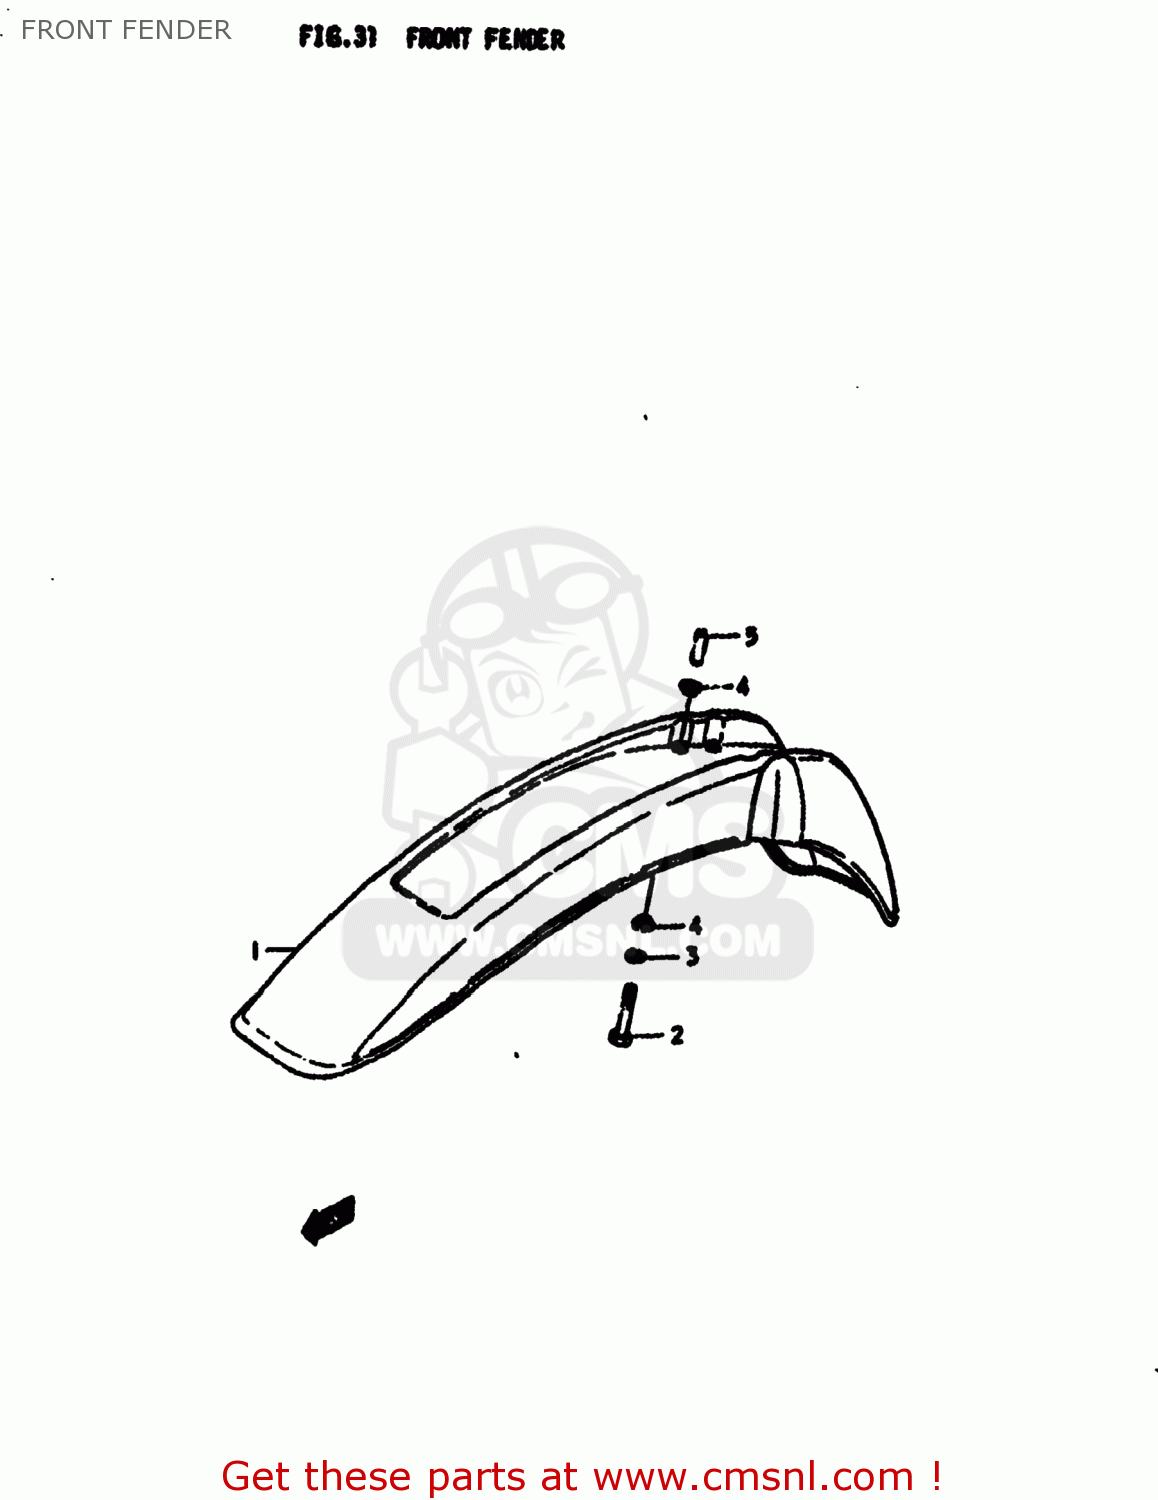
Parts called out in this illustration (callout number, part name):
1	FENDER,FRONT
2	BOLT
3	LOCK WASHER
4	WASHER
5	SPACER (6.8X10X27.4)
